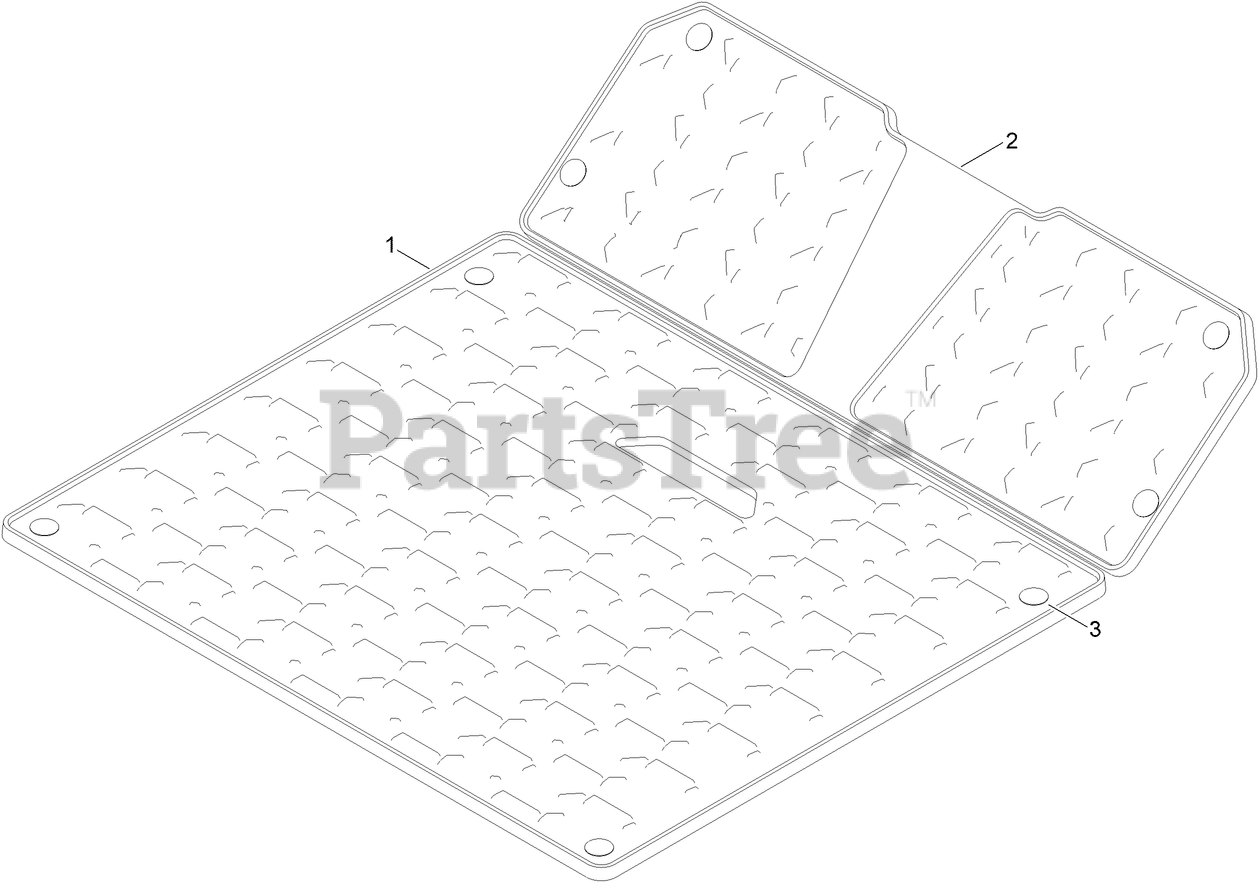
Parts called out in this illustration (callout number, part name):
1	FLOOR MAT
2	FLOOR MAT, TC
3	PLUG-PLASTIC
